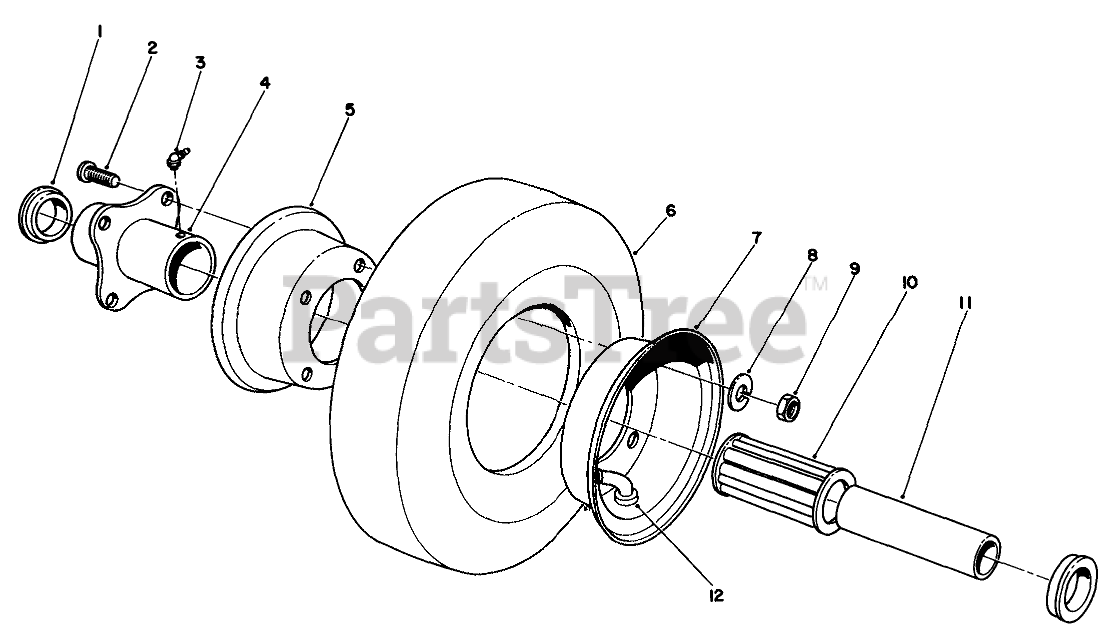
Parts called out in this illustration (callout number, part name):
1	RETAINER
2	WHEEL BOLT
3	FITTING-GREASE
4	HUB-CENTERED
5	WHEEL HALF-FEMALE
6	TIRE-8 Inch (4-PLY)
7	WHEEL HALF-MALE
8	WASHER-LOCK
9	NUT-HEX
10	BEARING-ROLLER
11	Bushing-Spanner
